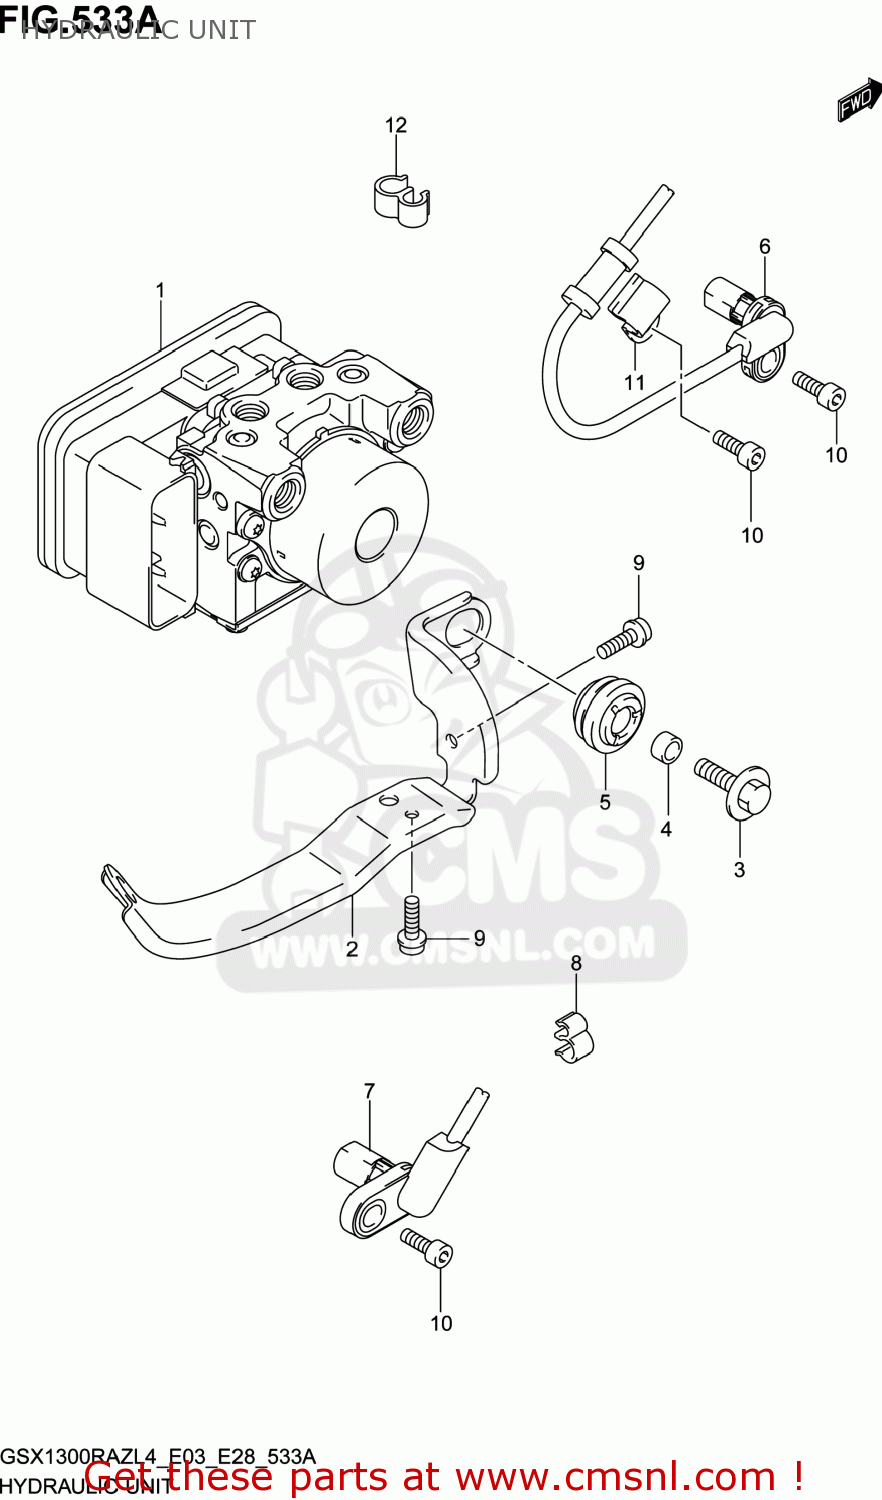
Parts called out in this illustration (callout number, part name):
1	UNIT ASSY,HYDRAULIC ABS
2	HOLDER,HYDRAULIC UNIT ABS
3	BOLT,HYDR UNIT MTG
4	SPACER,HYDR UNIT MTG
5	RUBBER
6	SENSOR,FR WHEEL ABS
7	SENSOR,RR WHEEL ABS
8	CLAMP
9	BOLT
10	BOLT
11	CLAMP,ABS SENSOR FR
12	CLAMP(L:145)
